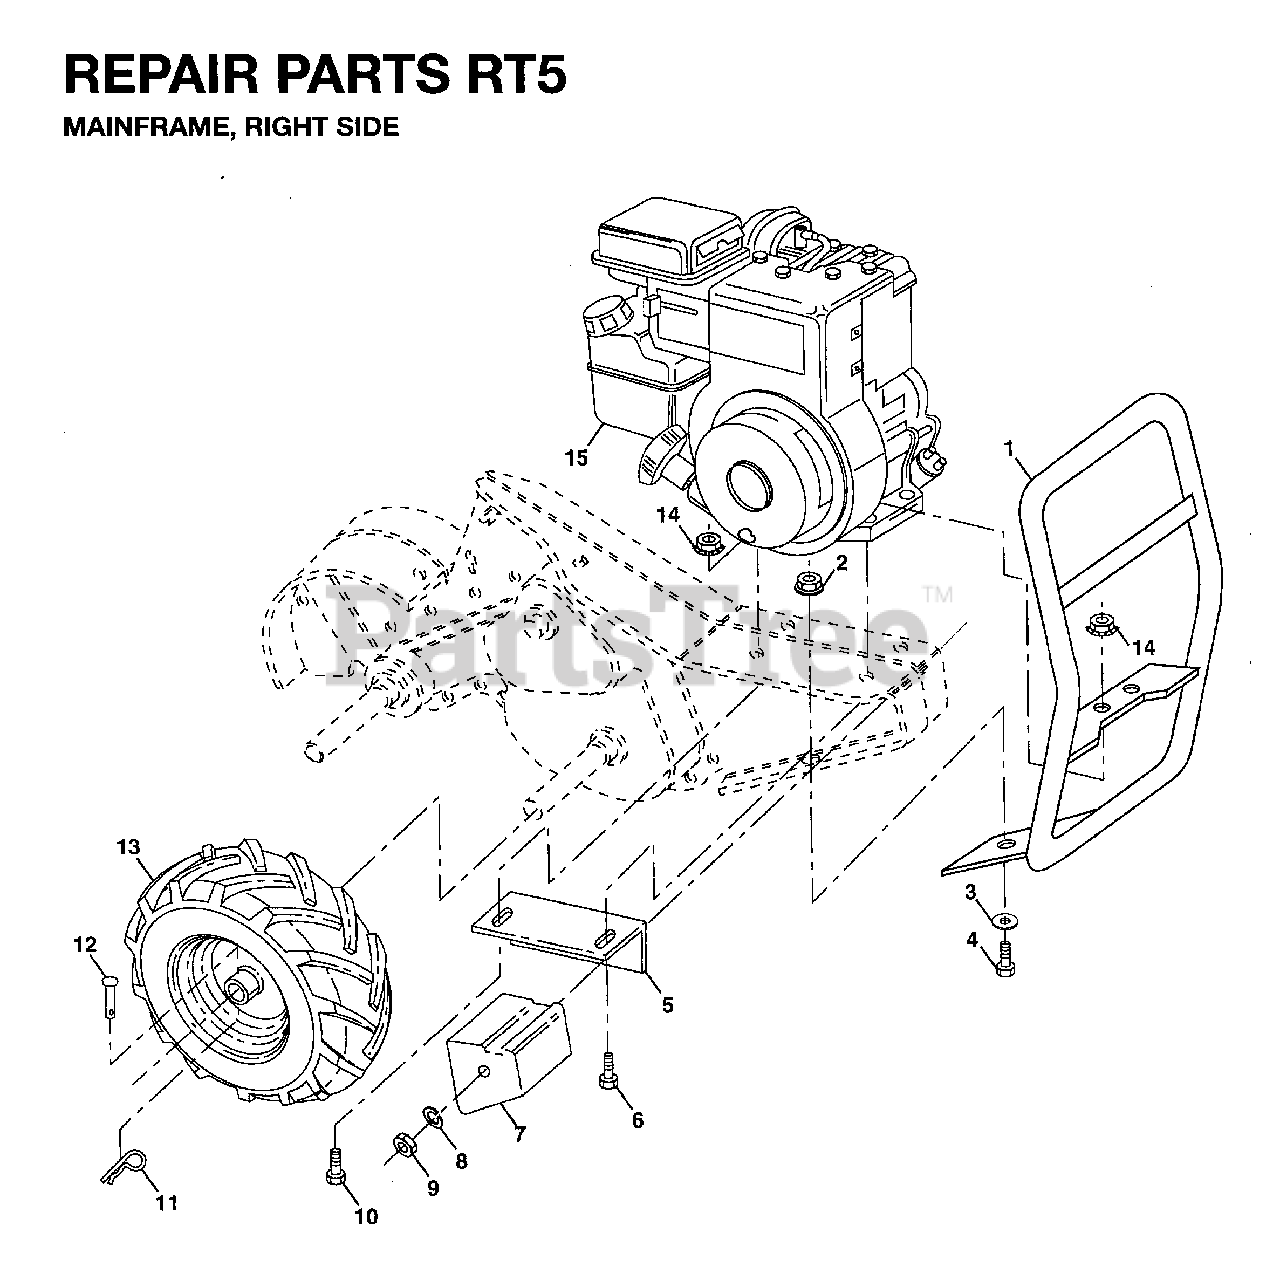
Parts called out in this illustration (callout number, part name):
1	BUMPER
2	LOCKNUT
3	WASHER - 15X7.3X1.6
4	BOLT
5	BRACKET RH CRT
7	COUNTERWEIGHT, RH
8	WASHER, LOCK 3/8
9	NUT.HEX.3/8-16UNC
10	HEX BOLT
11	RETAINER M
12	RIVET,DRILLED
14	LOCKNUT
5320651-39	VALVE STEM LT
5321289-52	WHEEL.8X2-3/4.TILLER /RIM ONLY
